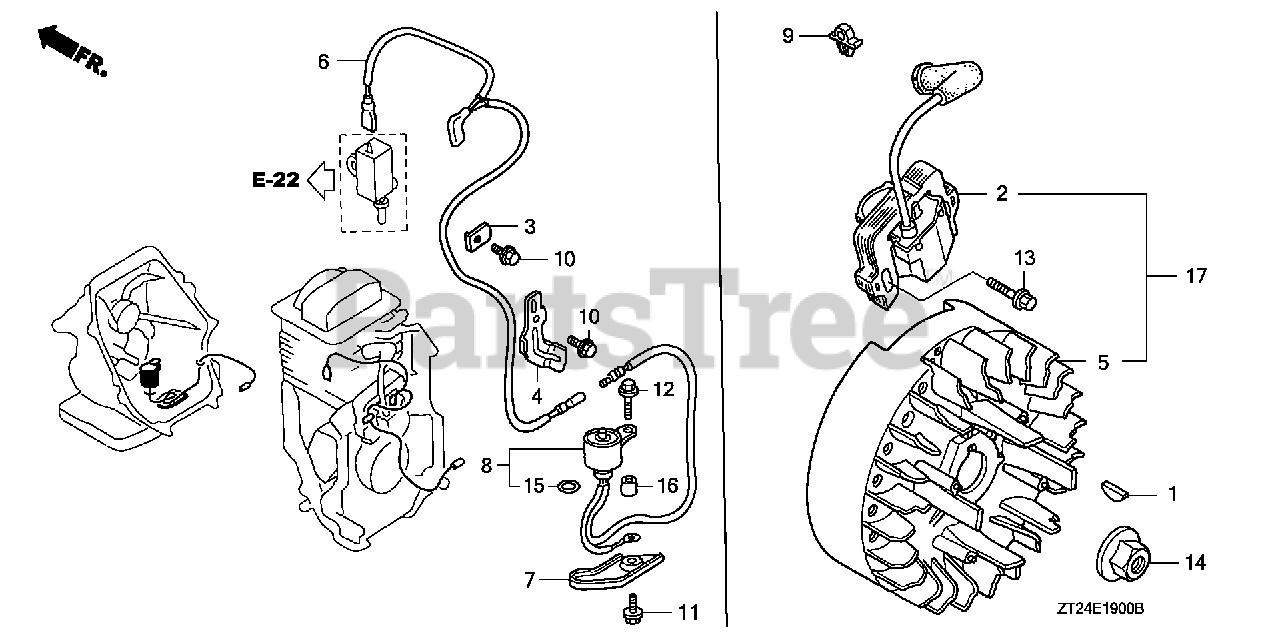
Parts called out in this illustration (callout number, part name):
1	KEY, SPECIAL WOODRUFF (25X18)
2	COIL ASSY., IGNITION (USE FOR F/W OF TEC) (TEC) Use up to Engine SN 3747197.
2	COIL ASSY., IGNITION (PHELON) (USE FOR F/W OF PHELON)
3	CLAMP, STOP SWITCH WIRE
4	CLAMP, WIRE
5	FLYWHEEL COMP. (TEC) (USE FOR IGN. COIL OF TEC) Use up to Engine SN 3747197.
5	FLYWHEEL COMP. (PHELON) (USE FOR IGN. COIL OF PHELON) (USE FOR PHELON IGNITION COIL)
6	WIRE, STOP SWITCH
7	PROTECTOR, SWITCH
8	SWITCH, OIL LEVEL
9	HOLDER, STOP SWITCH WIRE
10	BOLT, FLANGE (6X12) (CT200)
11	BOLT, FLANGE (6X14) (CT200)
12	BOLT, FLANGE (6X28) (CT200)
13	BOLT, FLANGE (6X20) (CT200)
14	NUT, SPECIAL (14MM)
15	O-RING (11.8X2.4)
16	COLLAR (6.6X13.8X14.5)
17	FLYWHEEL KIT Use up to Engine SN 3747197.
